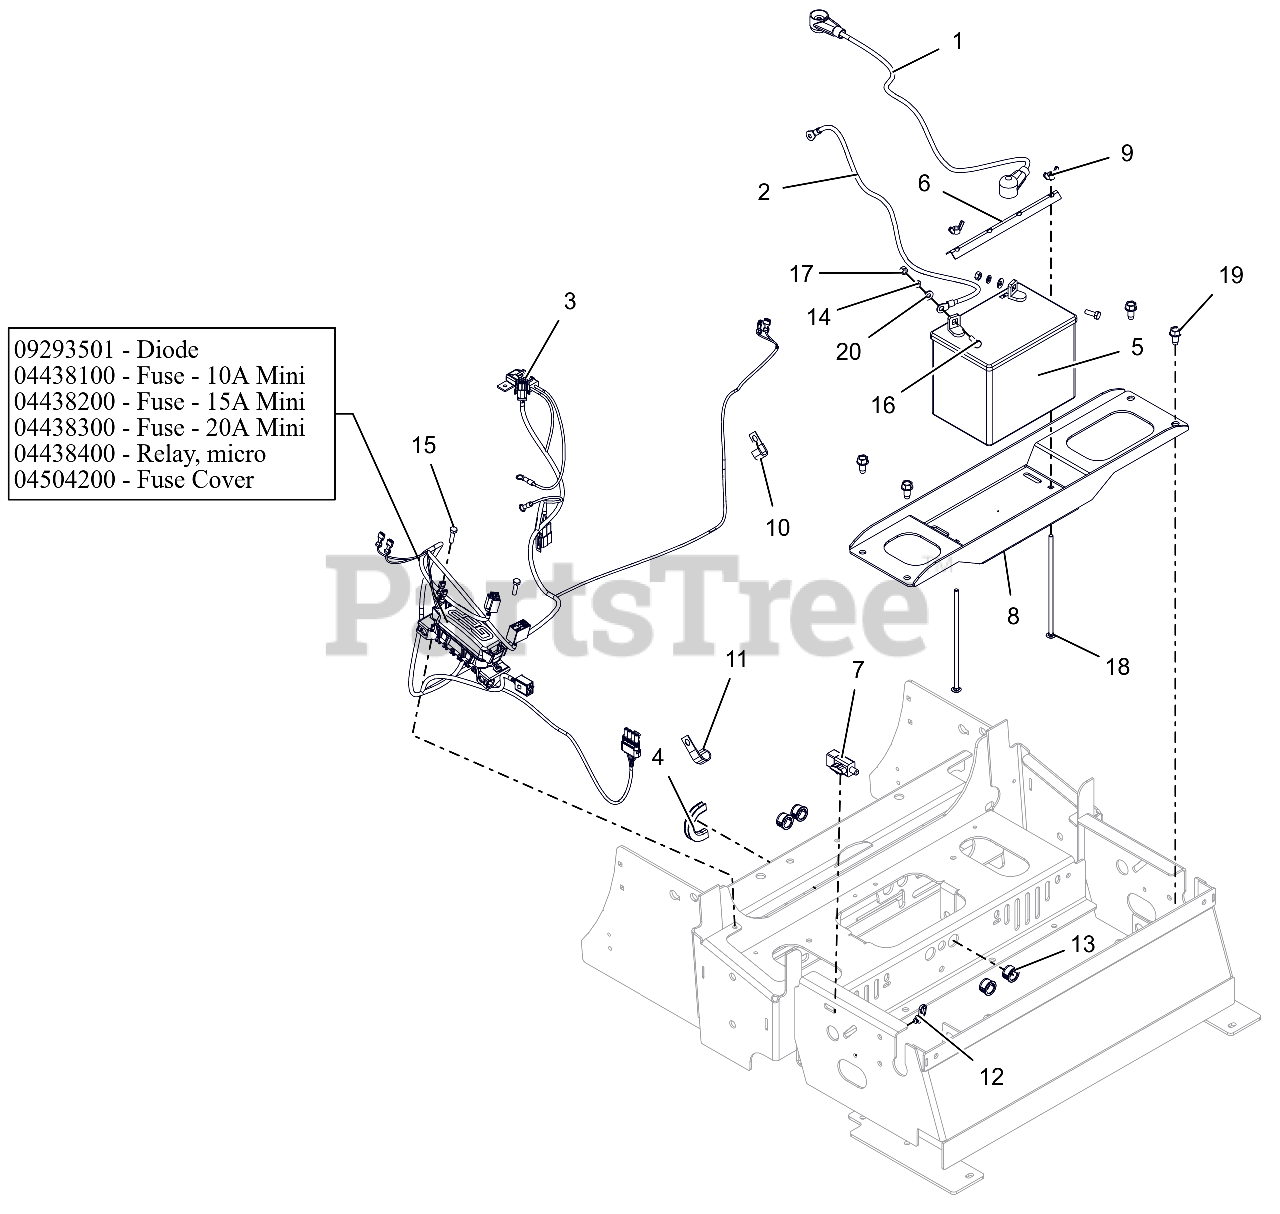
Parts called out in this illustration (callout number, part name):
1	CABLE - POS BATT W/BOOTS 6X35
2	CABLE-NEGATIVE BATTERY 35.00"
3	HARNESS, PT200/400 EFI WIRING
3	DIODE, CONNECTOR SHELL
3	FUSE,10 AMP MINI-ATC
3	FUSE,15 AMP MINI-ATC
3	FUSE,20 AMP MINI ATC
3	RELAY,MICRO5 TERML W/RESISTOR
3	COVER, HARNESS FUSE/RELAY MOD
4	STRIP, COWL
5	BATTERY, 300 CCA 10U1L
6	HOLD DOWN
7	SWITCH, SNAP IN - N.O./N.O.
8	PT200/400 BATTERY TRAY - RED
9	NUT, LK-WING .25-20 ZCC
12	CABLE TIE W/ TREE (.25 HOLE)
13	BUSH, PANEL SNAP .687X.875X.56
14	WSHR,LK-REG .250X.062 ZCC
15	BLT, HEX M6-1.0 X 25 G8.8 ZCC
16	BLT, HEX .25-20X.75 G5 ZCC
17	NUT-STD .250-20 G2 ZCC
18	BTL,RHSN .250-20 X 7.5 G5 ZCC
19	SCR,TAP .375-16X.75 HWH TR ZCC
20	WSHR,FLT .281X.625X.065 ZCC
